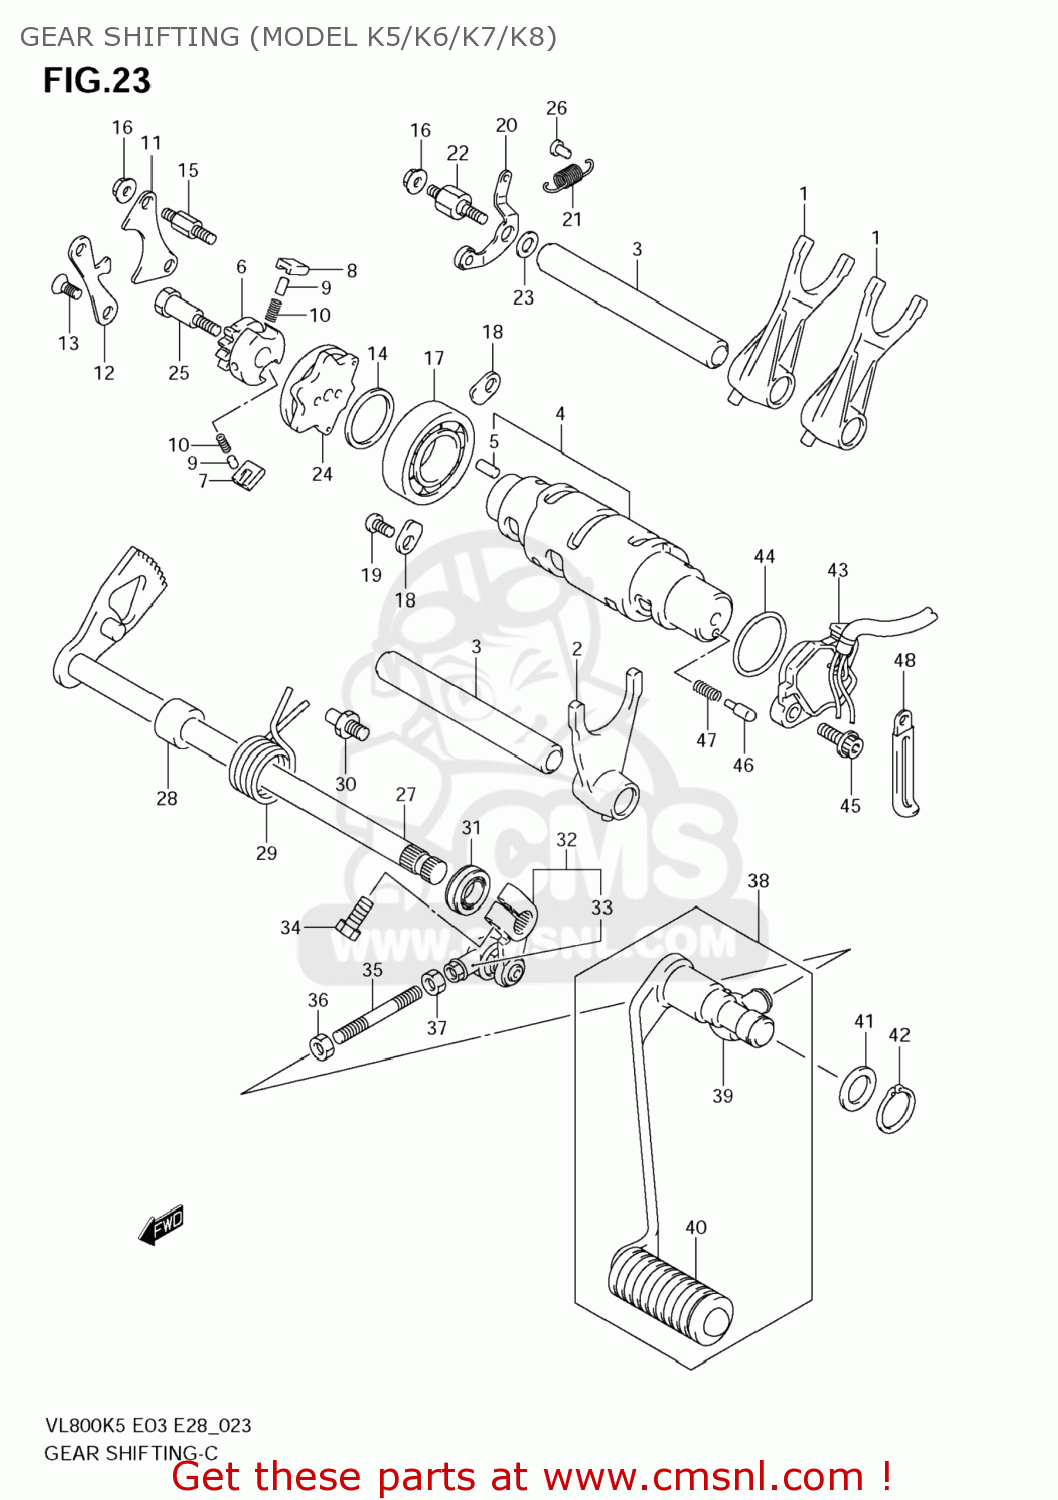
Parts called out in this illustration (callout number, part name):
1	FORK,GEAR SHIFT NO.1
2	FORK,GEAR SHIFT NO.2
3	SHAFT,GEAR SHIFT FORK(L:115)
4	CAM,GEAR SHIFT
5	PIN
6	GEAR,GEAR SHIFT CAM DRIVEN
7	PAWL,GEAR SHIFT NO.1
8	PAWL,GEAR SHIFT NO.2
9	PIN(5X8)
10	SPRING
11	LIFTER,GEAR SHIFT POLE
12	GUIDE,GEAR SHIFT CAM
13	SCREW(6X12)
14	WASHER(25X32X3)
15	BOSS,SHIFT POLE LIFTER
16	NUT
17	BEARING(25X47X8)
18	RETAINER
19	BOLT(6X12)
20	STOPPER,GEAR SHIFT CAM
21	SPRING
22	SUPPORT,CAM STOPPER ARM
23	WASHER
24	PLATE,GEAR SHIFT CAM
25	PIN,SHIFT CAM DRIVEN GEAR
26	RIVET
27	SHAFT,GEAR SHIFT
28	SPACER(12X20X15.3)
29	SPRING
30	STOPPER,GEAR SHIFT ARM
31	OIL SEAL
32	ARM,GEAR SHIFT SHAFT
33	COVER,DUST
34	BOLT
35	ROD,GEAR SHIFT LINK
36	NUT
37	NUT
38	LEVER ASSY,GEAR SHIFT
39	COVER,DUST
40	RUBBER,GEAR SHIFT PEDAL
41	WASHER(14.5X22X1.6)
42	CIRCLIP
43	BASE ASSY,GEAR
44	O RING(D:2.4,ID:25.7)
45	BOLT
46	PIN(5X15.5)
47	SPRING
48	CLAMP(L:45)
